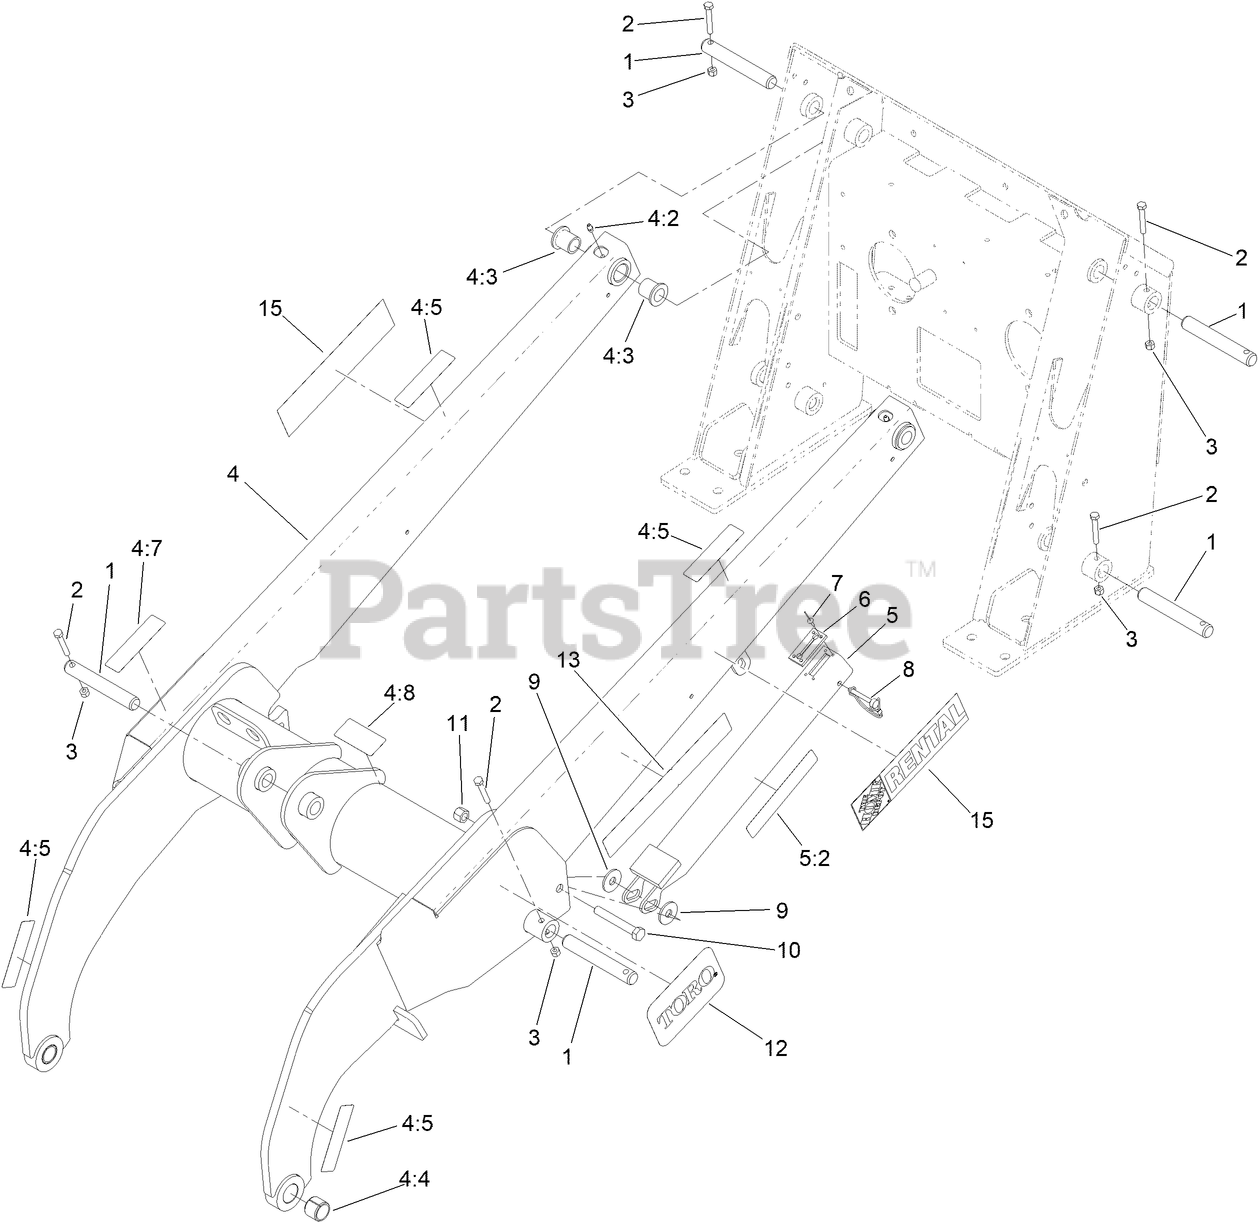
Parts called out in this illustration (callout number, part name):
1	PIN-LOCKING
2	SCREW-HH
3	NUT-LOCK, NI
4	LOADER ARM ASM
4:2	FITTING-GREASE
4:3	BUSHING
4:4	BUSHING-TENSION
4:5	DECAL-WARNING, PINCH
4:7	DECAL-CAUTION
4:8	DECAL-NO RIDER
5	LOCKING ARM ASM
5:2	DECAL-DANGER
6	STOP-RUBBER
7	RIVET
8	PIN-HITCH
9	WASHER-RUBBER
10	SCREW-HH
11	NUT-LOCK, NI
15	DECAL - HDHLW3X10
